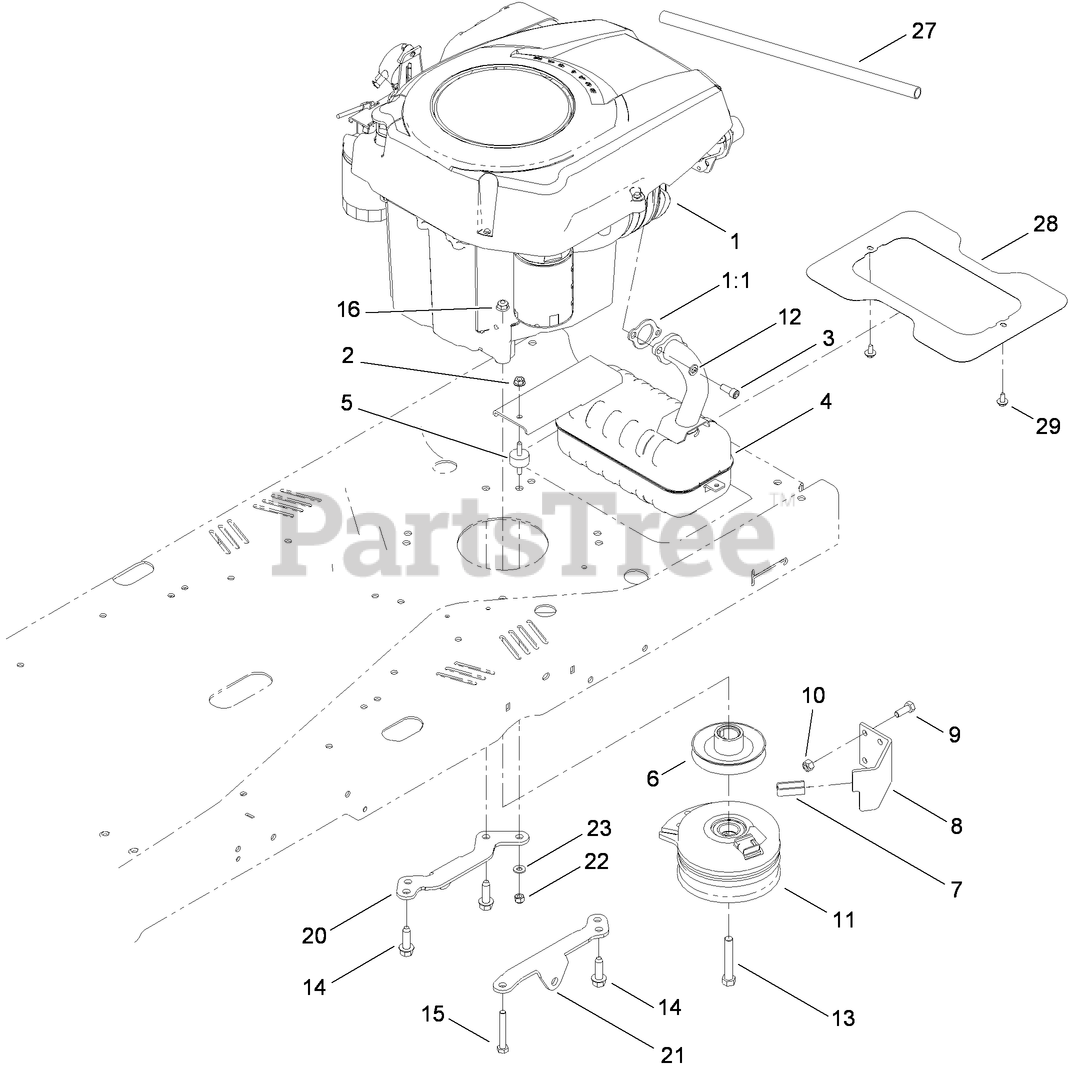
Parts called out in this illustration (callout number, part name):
1:1	GASKET-EXHAUST
2	NUT-HF
3	SCREW-HSH
4	MUFFLER
5	ISOLATOR
6	PULLEY-ENGINE
7	BUMPER-PAD
8	STOP-CLUTCH
9	SCREW-HH
10	NUT-LOCK, NI
11	CLUTCH-ELECTRIC
12	WASHER-LOCK
13	SCREW-HH
14	SCREW-THD
15	SCREW-HH
16	NUT-HF, NI
20	SUPPORT-HYDRO, RH
21	SUPPORT-HYDRO, LH
22	NUT-LOCK, NI
23	WASHER-FLAT
27	TUBE-DRAIN, OIL
28	SHIELD-HEAT
29	SCREW-HHFTF
